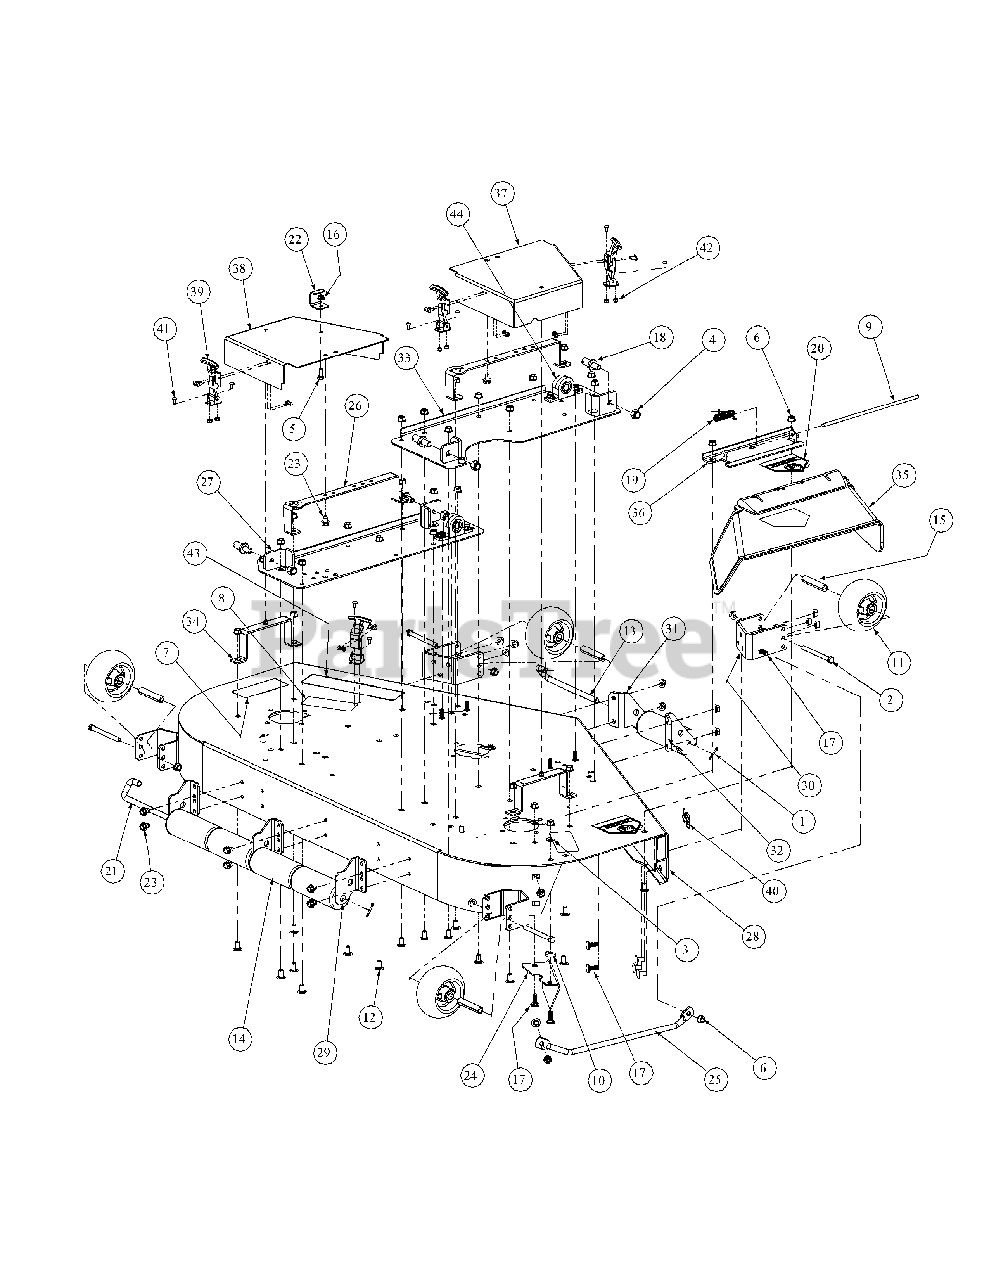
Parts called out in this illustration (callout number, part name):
1	Cotter Pin, .125 Dia x 1.0
2	Hex Cap Screw, 3/8-16, 3.75
3	Flat Washer, 3/8
4	Lock Nut, Nylon Insert, 1/2-13
5	Hex Cap Screw, 5/16-18 x 3/4
6	Hex Nut, 3/8-16 Flange Lock
7	Decal Rotating Blade
8	Decal, Warning Shield Missing
9	Defllector Chute Rod
10	Idler Washer
11	Complete Wheel, 5.00 Dia.
12	Carriage Bolt, 3/8-16 x .75 Lg.
13	Roller Pin. 1/2 Dia. x 7.31 Lg.
14	Front Roller
15	Wheel Spacer
16	Hexflange Lock Nut, 5/16-18
17	Carriage Bolt, 3/8-16 x 1
18	Pin, 5/8 Dia. x 1.2 Lg.
19	Spring Torsion, 0.4 ID x 2.16 LG
20	Decal, Danger Hands and Feet
21	Roller Pin
22	Tension Rod Stop Bracket
23	Hex Index Washer Screw, 3/8-16, .5
24	Chute Bracket
25	Finger Guard
26	Cover Support
27	Left Hand Mount, Deck Bracket Assembly
28	54 Deck Assembly
29	Roller Mount Bracket
30	Anti-Scalp Wheel, Front Mount Bracket
33	Deck Bracket Assembly
34	Outer Belt Cover Support Assembly
35	Deflector Chute
36	Deflector Chute Bracket
37	Right Hand Belt Deck Cover Weldment
38	Left Hand Belt Deck Cover Weldment
39	T-Handle Draw Latch
40	Decal, 54"
41	Phillips Head Screw, 10-32
42	Lock Nut, Nylon Insert, 10-32
43	Mower Deck Label
44	Pillow Block
